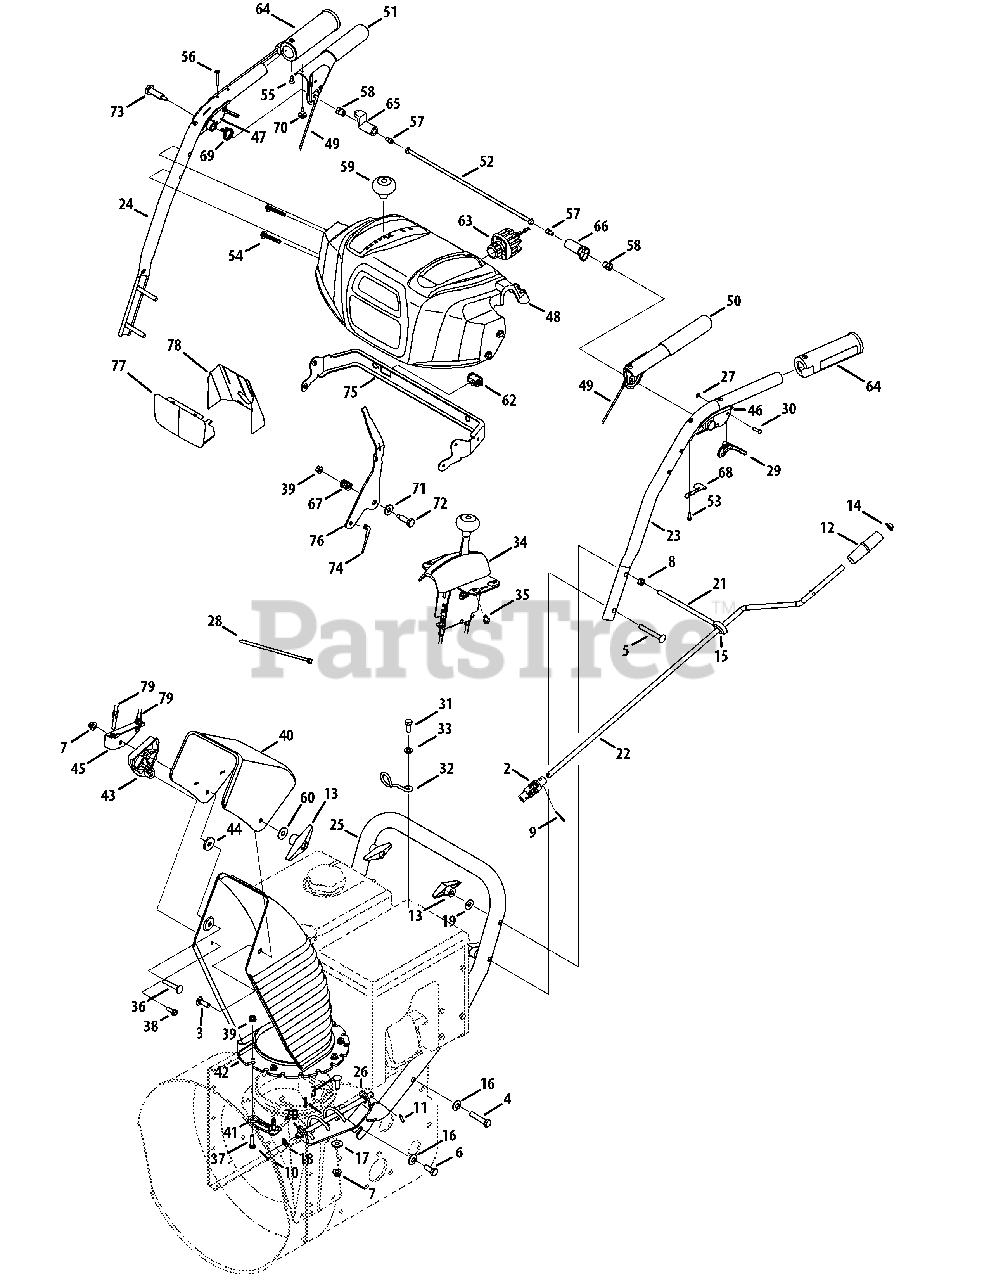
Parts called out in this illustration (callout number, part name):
1	Chute Crank Assembly
2	Joint Block Assembly
3	Screw, Carriage, 5/16-18 x 1.0
4	Screw, Hex, 3/8-16 x 2.00 Lock, Gr5
5	Screw, Carriage, 5/16-18 x 2.5
6	Screw, Hex, 3/8-16 x 1.0 Lock, Gr5
7	Flange Lock Nut, 5/16-18
8	Hex Nut, 5/16-18
9	Internal Cotter Pin
10	Internal Cotter Pin
11	Spring Pin
12	Knob, Crank
13	Knob, Wing Nut, 5/16-18
14	Cap, Push, 3/8
15	Grommet, Rubber
16	Washer, Bel, .375 x .87 x .063
17	Washer, Flat, .349 x .879 .063
18	Washer, .375 x .738 x .063
19	Washer, Belleville, .34 x .872 x .06
20	Plastic Bushing, .380 I.D.
21	Eye Bolt
23	Handle, Upper - LH
24	Handle, Upper - RH
25	Handle, Lower
26	Chute Crank Bracket
27	Ring, Retainer
28	Cable Tie
29	Trigger
30	Pin, 3/16
31	Hex Head Screw, MB 1.25
32	Cable Guide
33	Flat Washer, .330 x .630 x .0635
34	2-Way Chute Control™ Assy
35	Hi-Lo Screw, 1/4-15 x 0.5
36	Bolt, Carriage, 5/16-18 x 1.75
37	Screw, 1/4-20 x 1.00
38	Hi-Lo Screw, 1/4-15 x .75
39	Flange Lock Nut, 1/4-20
40	Upper Chute
41	Chute, Flange Keeper
42	Lower Chute
43	Chute Tilt Cable Guide
44	Flat Washer
45	Cable Bracket
46	Handle Clutch Lock - LH
47	Handle Clutch Lock - RH
48	Handle Panel
49	Cable Assembly, Auger/Drive
49	Cable, Clutch
49	Spring, Extension
50	Handle Engage Assy - LH
51	Handle Engage Assy - RH
52	Rod Ass’y, Clutch Lock Pivot
53	Screw, #8-16 x 0.50
54	Screw, 1/4-20 x 1.625
55	AB Screw, #10-16
56	Screw, #10-24 x 0.375
57	Screw, 1/4-20 x.375
58	Shoulder Nut, 1/4-20
59	Shift Knob
60	Flat Washer, .349 x .879 x .063
62	Htd. Hand Grip on/off Switch
63	Light Socket
64	Heated Hand Grip
65	Lock Plate
66	Clutch Lock Cam
67	Compression Spring
68	Clutch Lock Spring
69	Torsion Spring
70	Rubber Bumper
71	Flat Washer, .385 x .87 x .06
72	Shoulder Screw
73	Shoulder Screw, 1/4-20 x 1.345
74	Speed Selector Cable
75	Panel Bracket
76	Shift Lever
77	Lens Panel
78	Reflector Label
79	Cable, Chute Tilt
